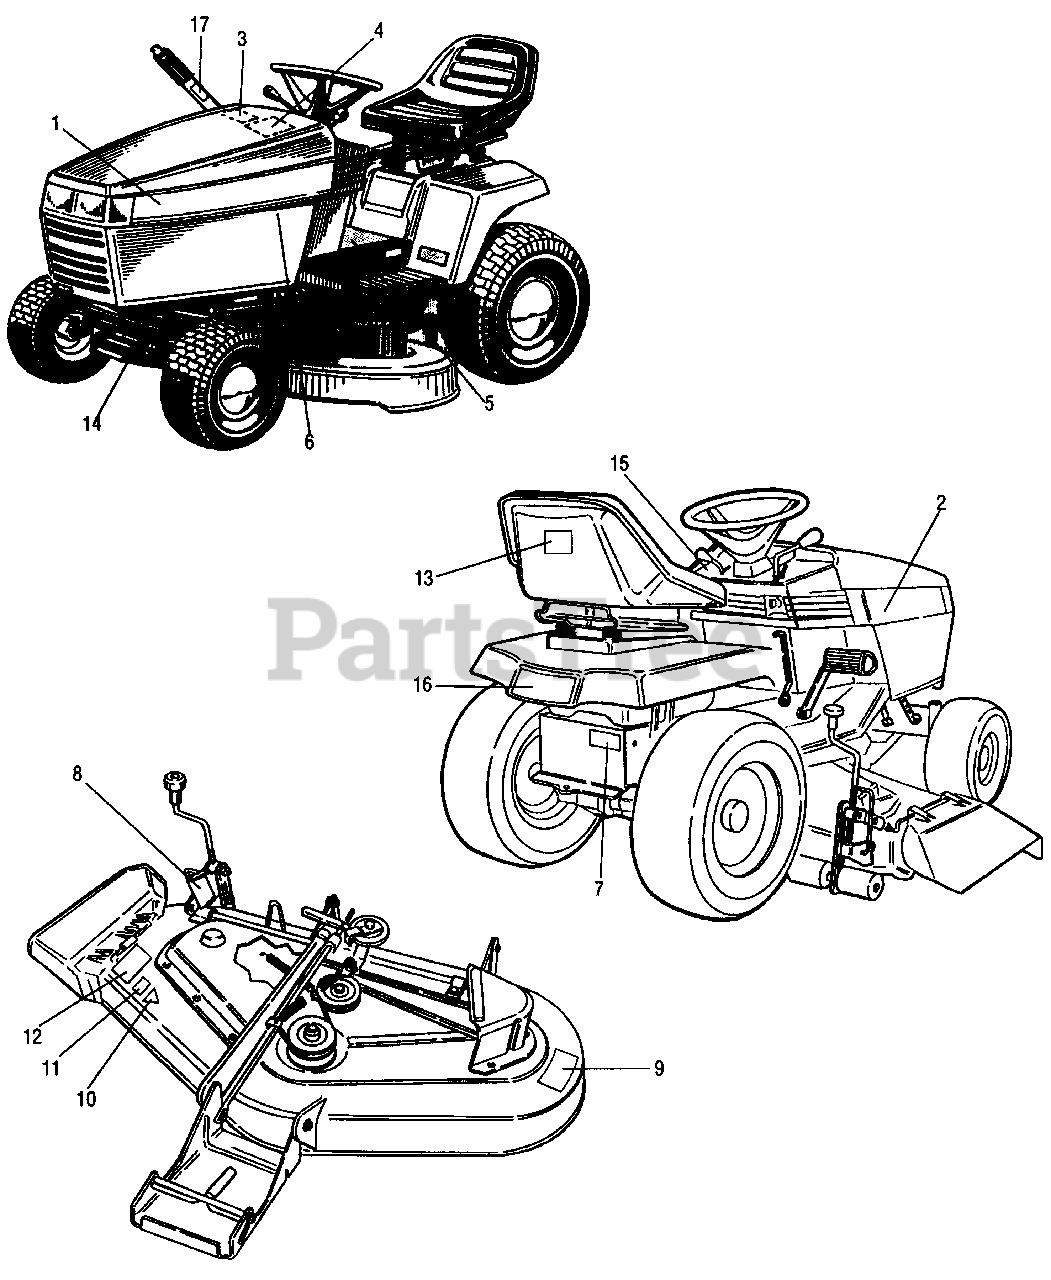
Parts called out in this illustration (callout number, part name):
1	DECAL, Hood, L.H.
2	DECAL, Hood, R.H.
3	DECAL, Paint
4	DECAL, Belt, Blade
5	DECAL, Operating Inst. (Hydro models only)
5	DECAL, Operating Inst. (Gear models only)
6	DECAL, Model Number, 18 HP
6	DECAL, Model Number, 16 HP Hydro
7	DECAL, Push Valve (Hydro models only)
8	DECAL, Mower Height
9	DECAL, Danger (Hand Under Deck)
10	DECAL, OPEI
11	DECAL, Cutting Width, 50"
11	DECAL, Cutting Width, 44"
12	DECAL, Danger (Chute in Place)
13	DECAL, Logo U.S.A.
14	I.D. PLATE
15	DECAL, Choke, Dash, (Gear models only)
16	DECAL, Simplicity
17	DECAL, Lift Lever (Gear models only)
